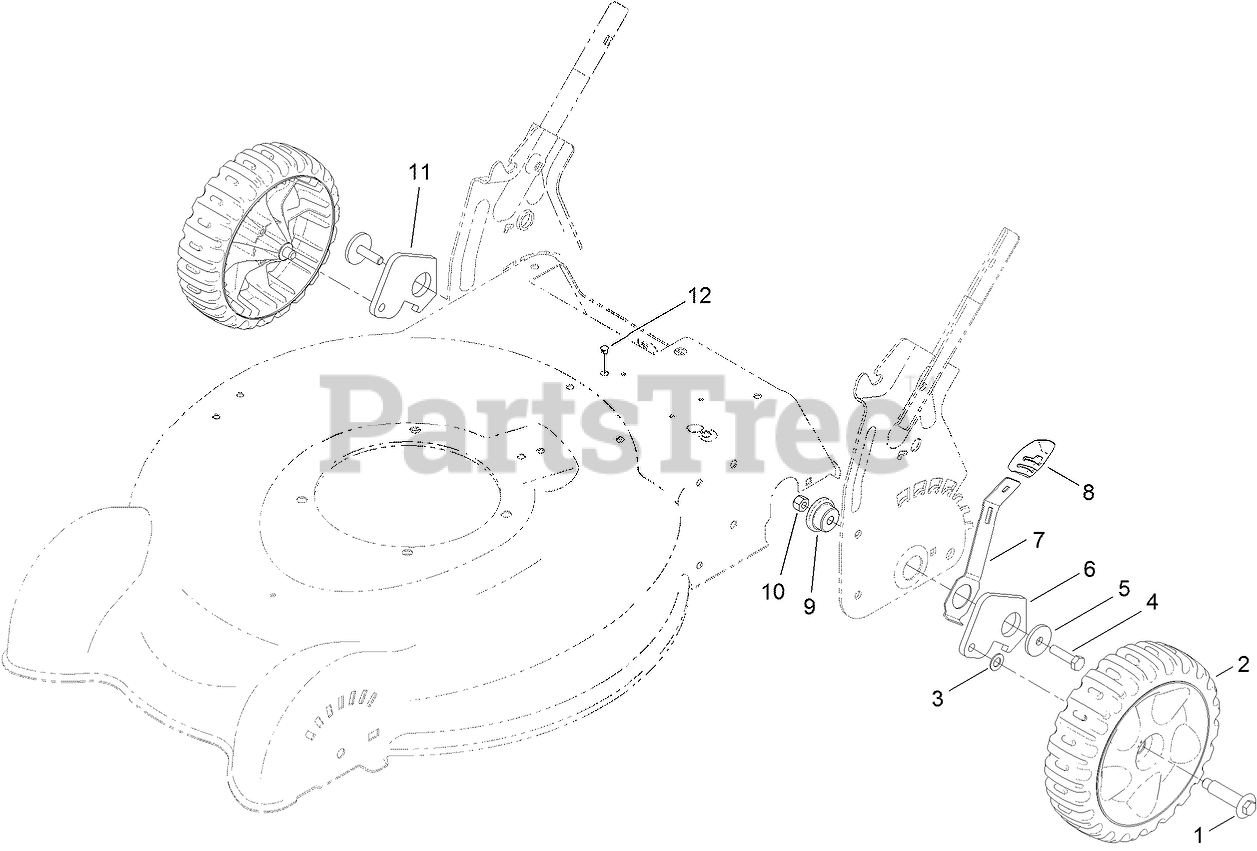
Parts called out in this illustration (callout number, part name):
1	BOLT-SHOULDER
2	8 INCH WHEEL AND TIRE ASM
3	WASHER
4	SCREW-HH
5	Washer-Flat
6	Arm-Pivot, Rear (LH)
7	Arm-Spring
8	Knob-Lever, HOC
9	Bushing-Mount, HOC
10	NUT-LOCK, NI
11	ARM-PIVOT, REAR (RH)
12	Plug-Dome
